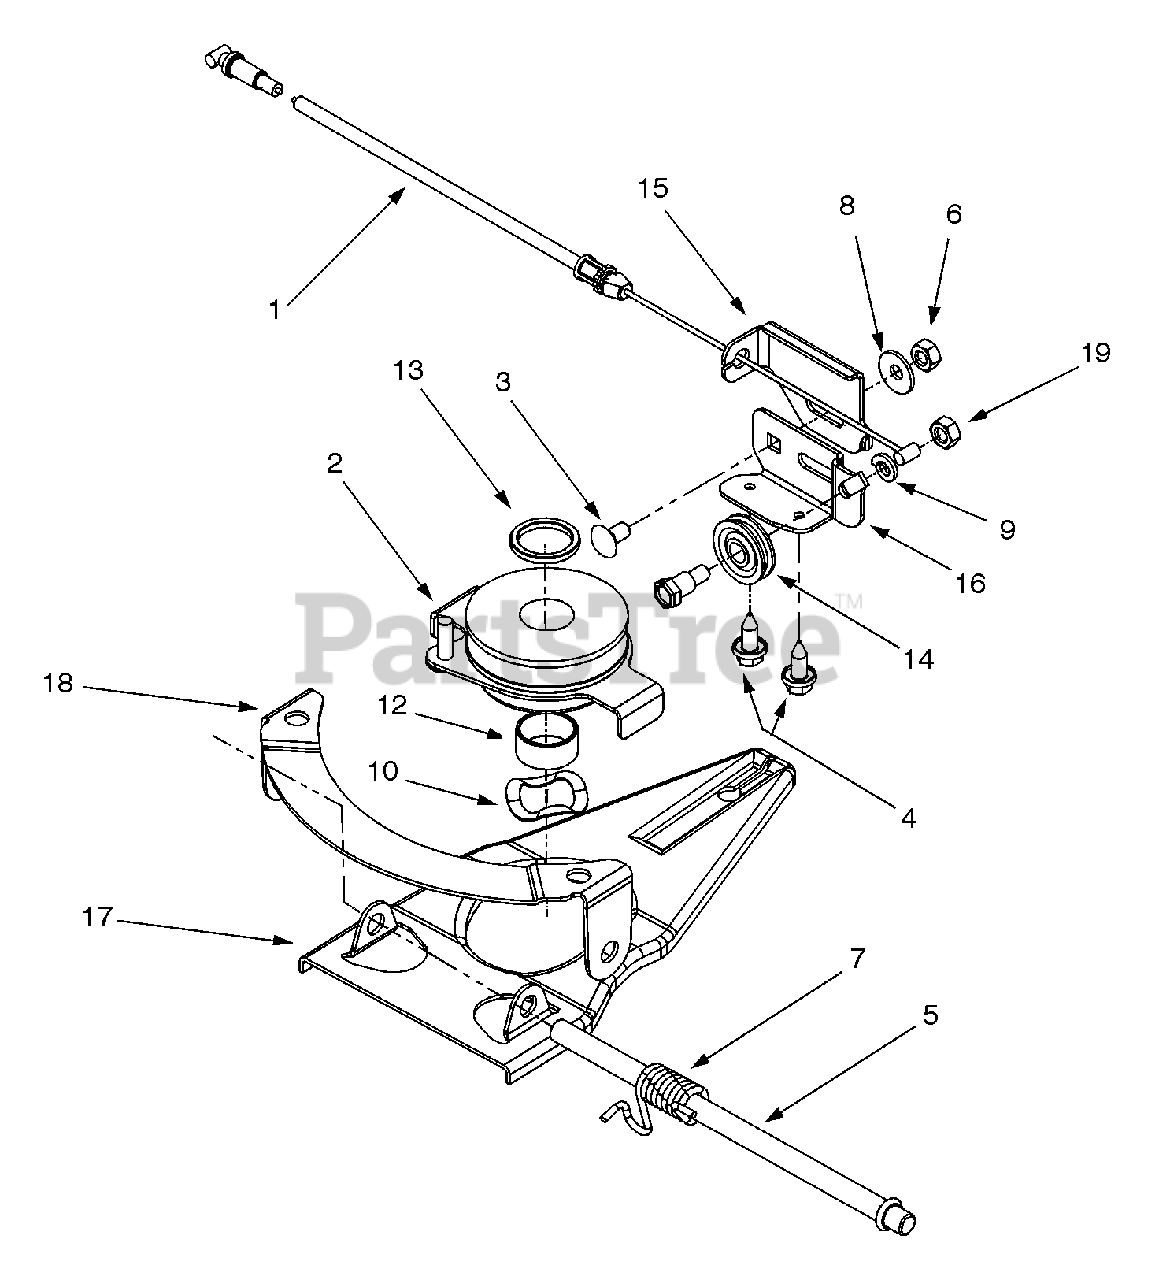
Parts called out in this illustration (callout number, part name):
1	Speed Selector Cable, 53"
2	Multi-speed Pulley Assembly
3	Carriage Bolt, 1/4-20 x .5
4	Self-tapping Screw, 1/4-20 x .625
6	Nut, 1/4-20
7	LH Torsion Spring
8	Bell Washer, .265 x .75 x .062
9	Lock Washer, 1/4
10	Wave Washer, 1.38 x .88 x .029
12	Sleeve Spacer, .88 ID x 1 OD x .48
13	Sleeve Spacer, .88 ID x 1.13 OD x .12
14	Cable Roller
19	Hex Nut, 1/4-20
